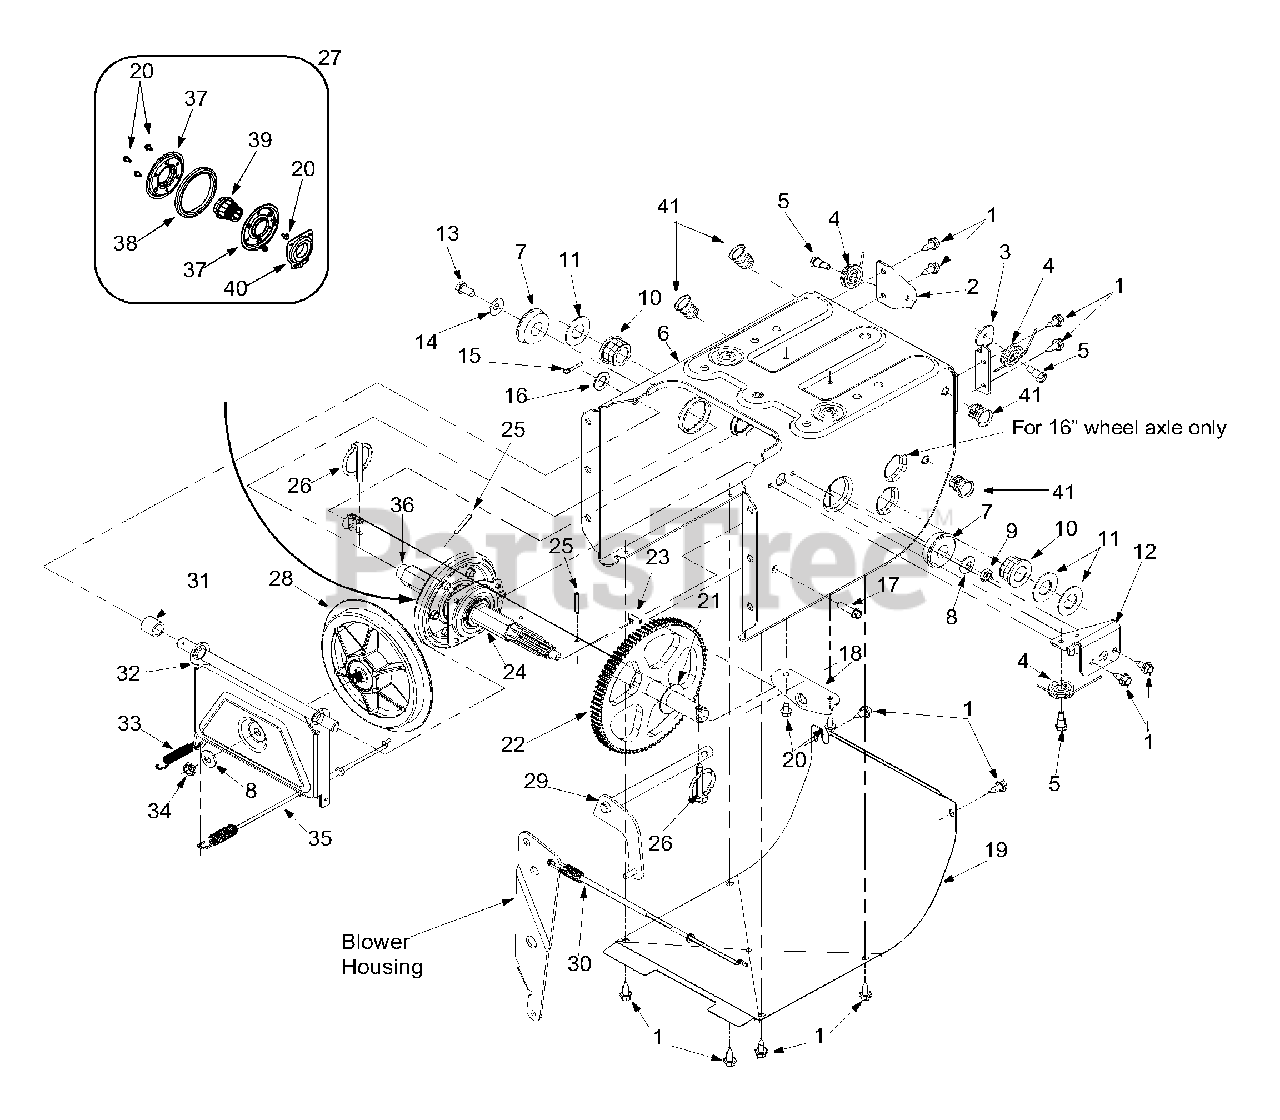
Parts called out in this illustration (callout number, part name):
1	Self-Tapp. Screw 1/4-20 x 0.5"
5	Hex Screw 1/4-28
8	Bell Washer
9	Lock Jam Nut
10	Hex Flange Bearing
11	Flat Washer
14	Bell Washer .340 ID x .872 OD
15	Cotter Pin
16	Flat Washer .536 ID x .930 OD
17	Hex Washer Screw 1/4-20 x .625"
21	Flat Washer .760 ID x .50 OD
24	7-Tooth Shaft
25	Roll Pin
26	Klik Pin
27	Friction Wheel Assembly
28	Friction Disc Wheel
29	Wheel Shift Rod Assembly
30	Drive Cable, Auger
31	Spacer
34	Jam Nut 3/8-24
35	Drive Cable, Clutch
36	22.2" Axle (Used w/13 x 4 tire)
36	21.4" Axle (Used w/13 x 5 tire)
37	Friction Plate
38	Friction Wheel Rubber
39	Friction Wheel Hub
40	Friction Wheel Bearing
41	Nut Insert
